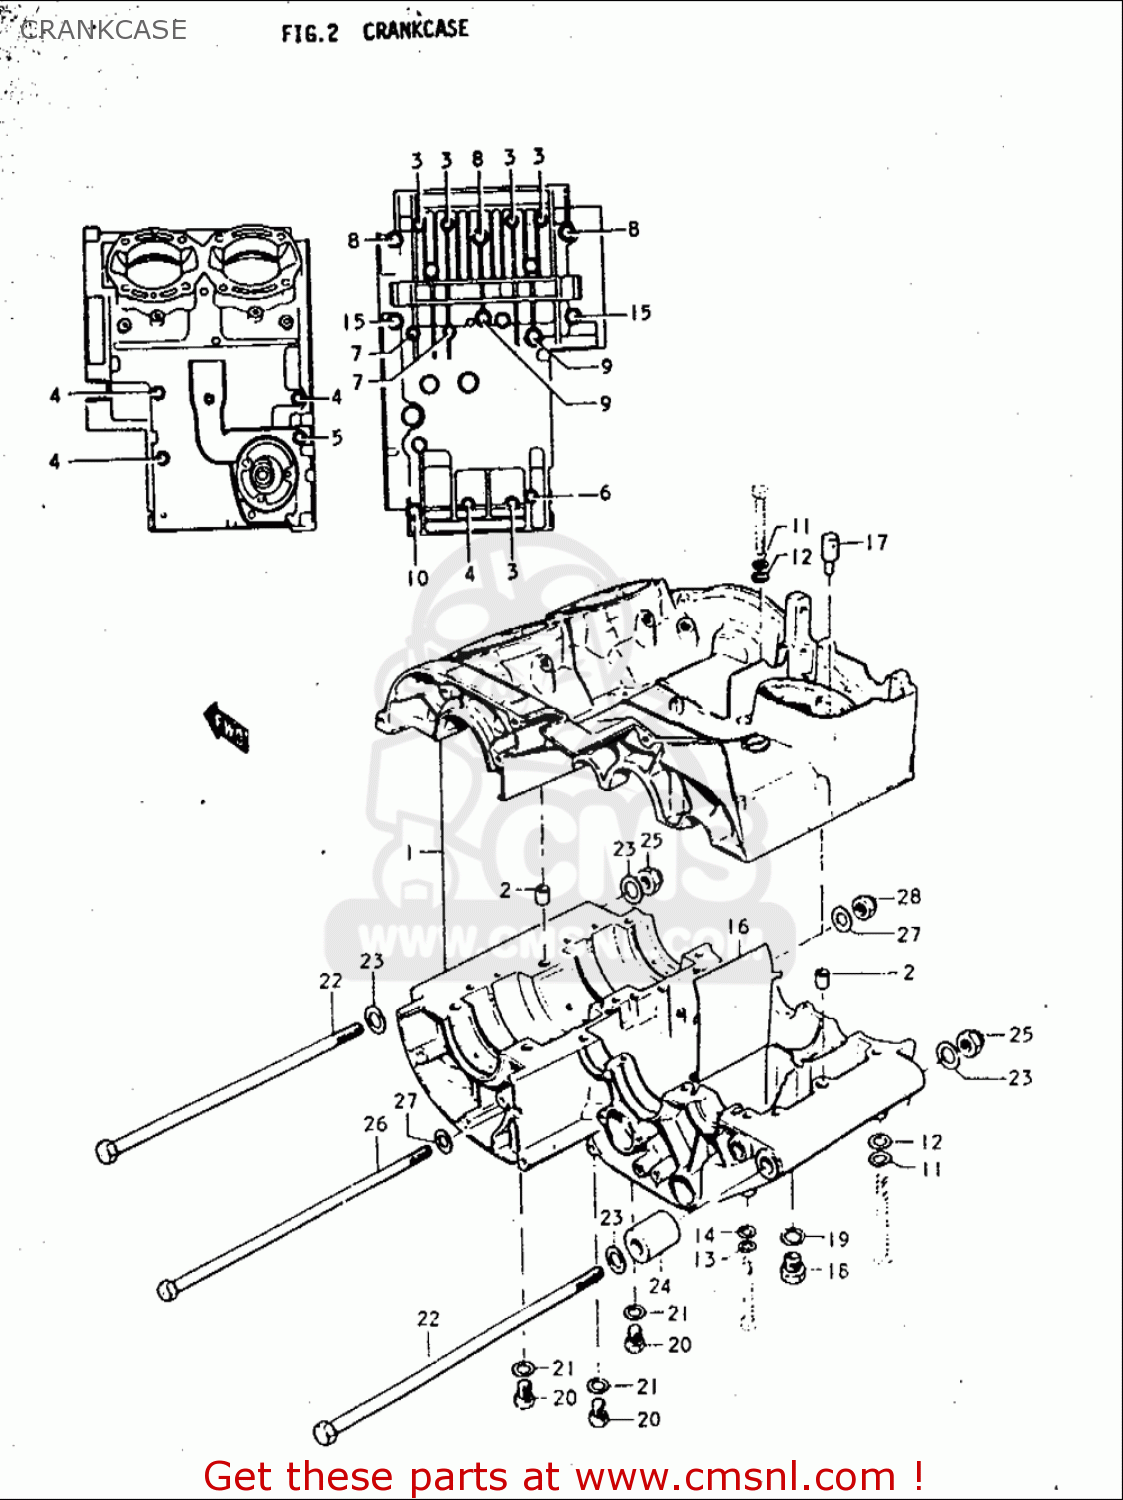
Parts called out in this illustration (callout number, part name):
2	PIN
3	BOLT
4	BOLT(6X60)
5	BOLT(6X65)
6	BOLT
8	BOLT
9	BOLT
10	BOLT
11	WASHER,LOCK
12	WASHER
13	WASHER,LOCK
14	WASHER
15	BOLT 8X100
17	PLUG,T/M BREATHER
18	PLUG(MAGNETO)
19	GASKET(14X19.2X2) (NAS)
20	PLUG
21	GASKET(10X14X3.6) (NAS)
23	WASHER
24	SPACER
25	NUT
27	WASHER
